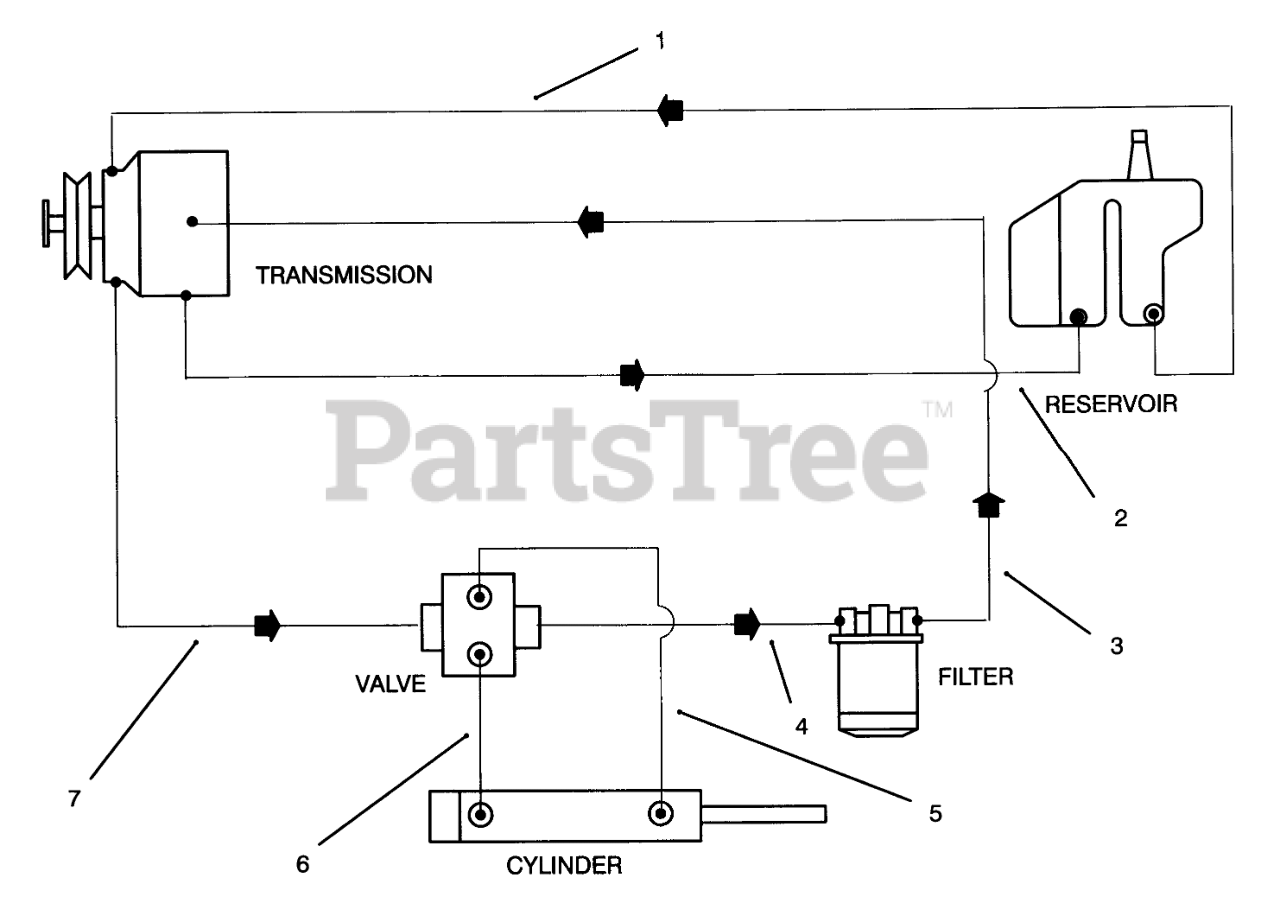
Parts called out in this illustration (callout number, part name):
1	HOSE ASM
2	TUBE ASM
3	HOSE ASM
4	HOSE ASM
5	HOSE ASM
6	HOSE ASM
7	HOSE ASM
